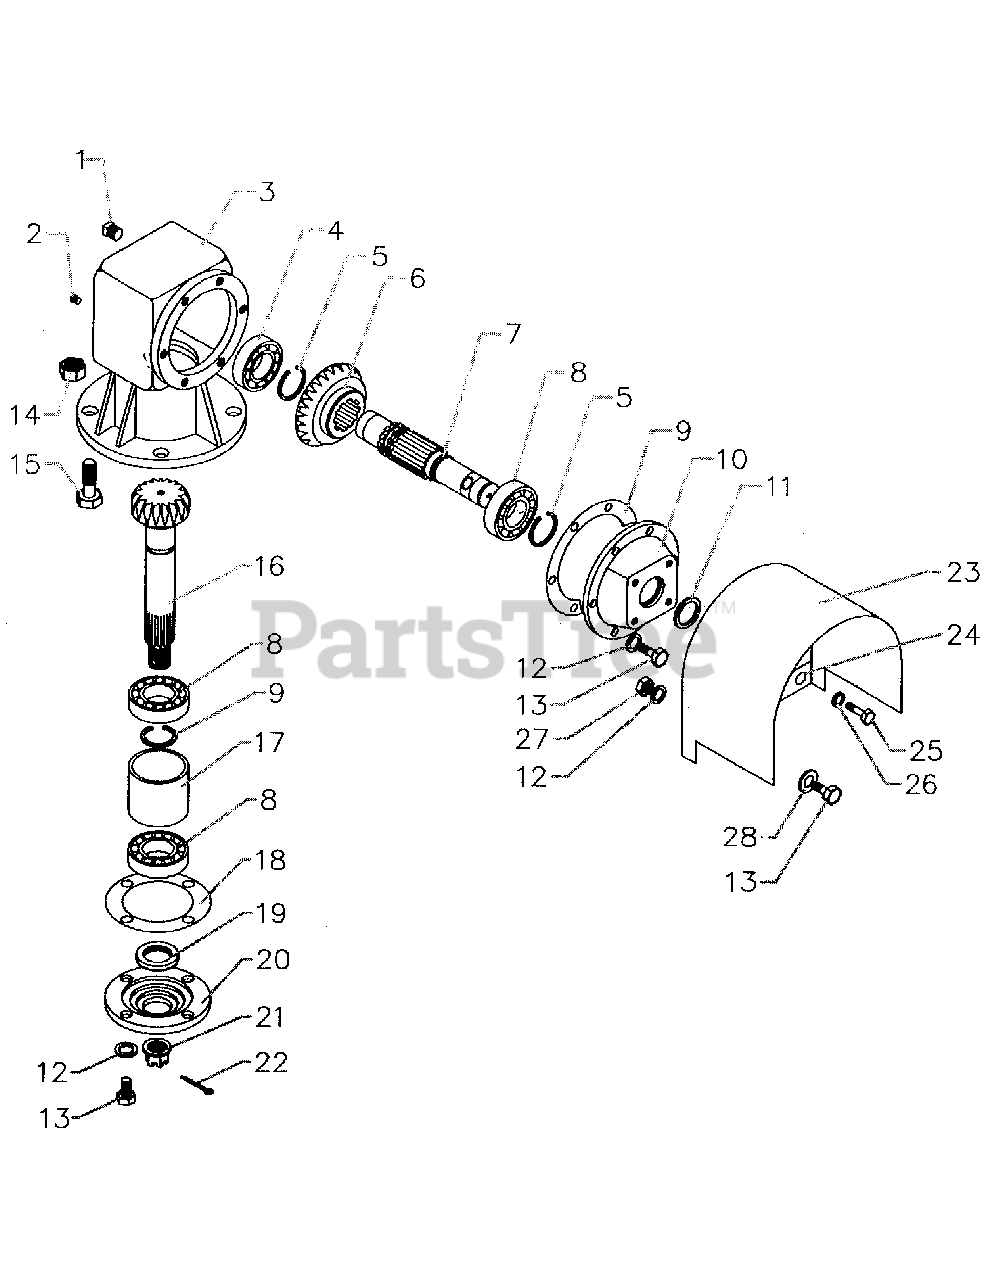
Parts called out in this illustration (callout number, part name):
1	FILL PLUG
2	CHECK PLUG
3	GEARBOX HOUSING
4	BEARING 6207
5	SNAP RING OUTER
6	RING GEAR
7	INPUT SHAFT
8	BEARING 6208
9	SHIM
10	GEARBOX COVER
11	OIL SEAL
12	LOCKWASHER 10MM
13	BOLT 10 X 25
14	STOVER NUT 16MM
15	BOLT 16 X 55
16	PINION GEAR
17	SPACER
18	SHIM
19	OIL SEAL
20	OUTPUT COVER
21	CASTLE NUT
22	COTTER PIN
23	SLIP CLUTCH SHIELDING
24	SHIELDING BRACKET
24	SLIP CLUTCH SHIELDING COMPLETE
25	BOLT 8 X 16
26	LOCKWASHER 8MM
27	HEX NUT 10MM
28	FLAT WASHER 10MM
